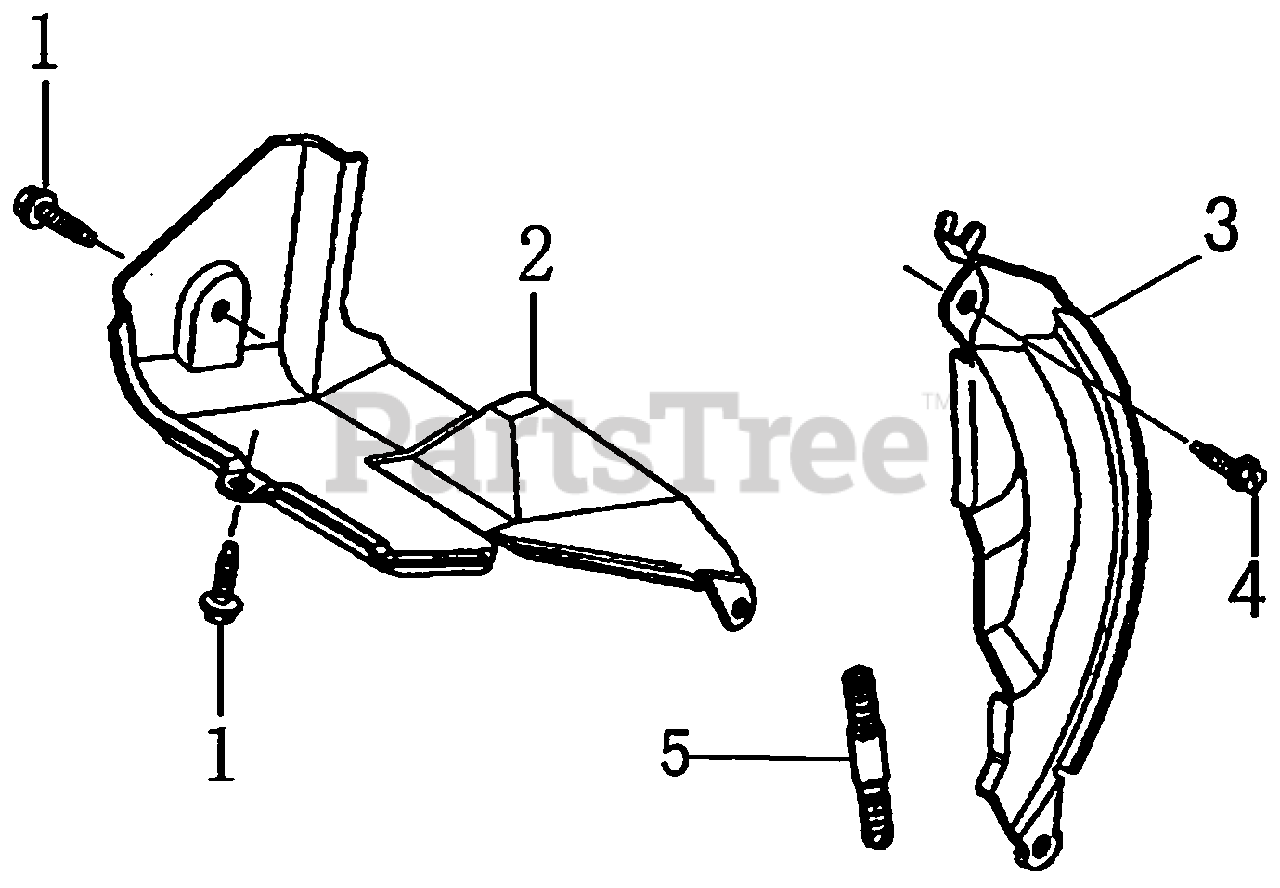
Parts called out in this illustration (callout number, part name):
1	BOLT, FLANGE 6×8
2	SHROUD COMP
3	PLATE, SIDE
4	BOLT, FLANGE, 6×20
5	BOLT, STUD
